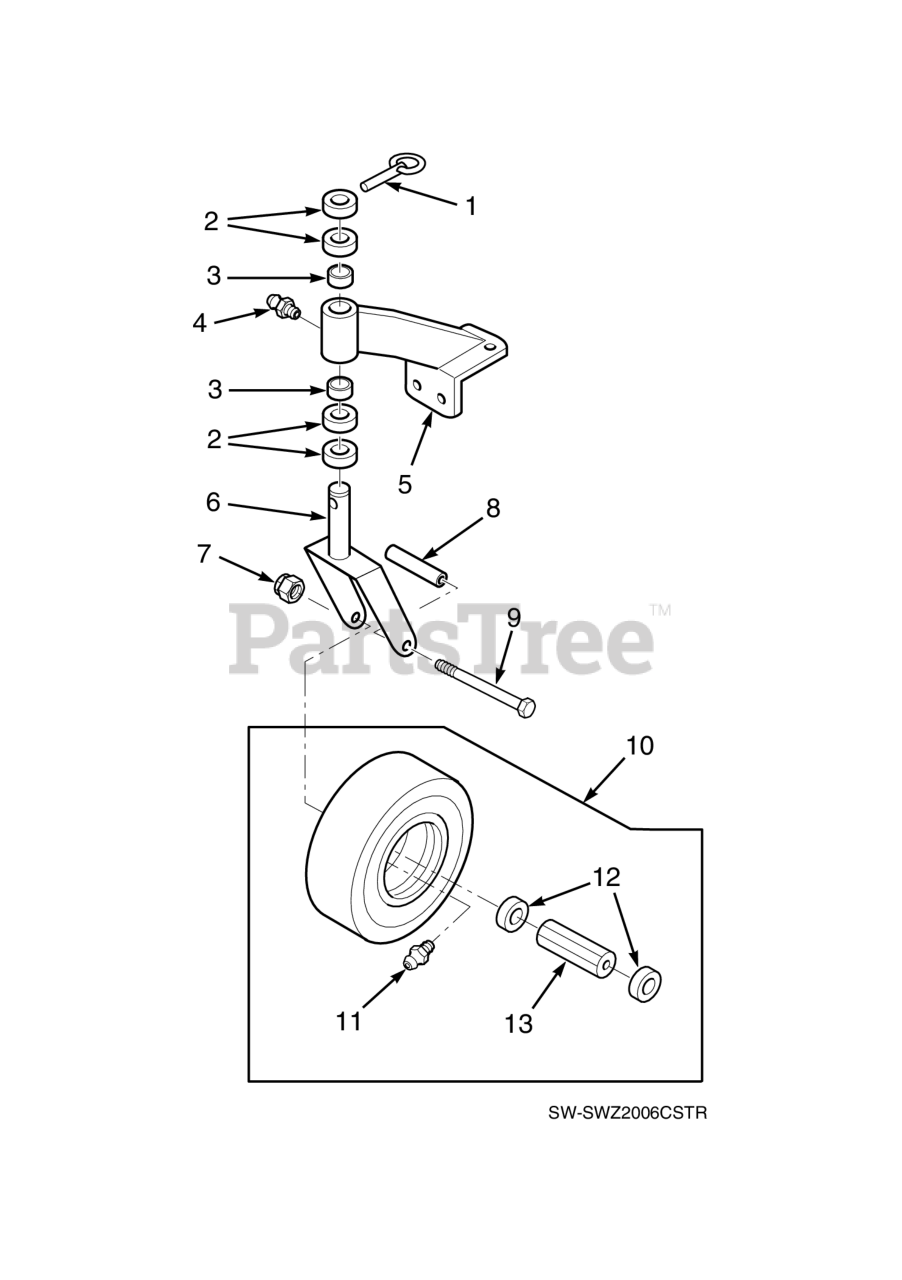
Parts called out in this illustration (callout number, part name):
1	Quick Pin, .438" Dia.
2	SPACER, CASTER YOKE, 1/2" THICK
3	Bronze Bushing, 7/8 ID x 1.0 Flanged
4	GREASE FITTING, STR. 1/4-28 SELF TAP.
5	Support Assembly
6	Caster Yoke Weldment
7	HEX LOCKNUT, ELASTIC STOP, 1/2-13
8	SLEEVE, CASTER WHEEL BEARING
9	Bolt, Hex Head 1/2-13 x 5-1/2" (Three Weights Installed)
10	REPLACED BY 9275
11	GREASE FITTING, 45 DEGREE 1/4-28
12	Retainer, Bearing, Caster Wheel
13	Roller Bearing, .625 x 3-1/4"
